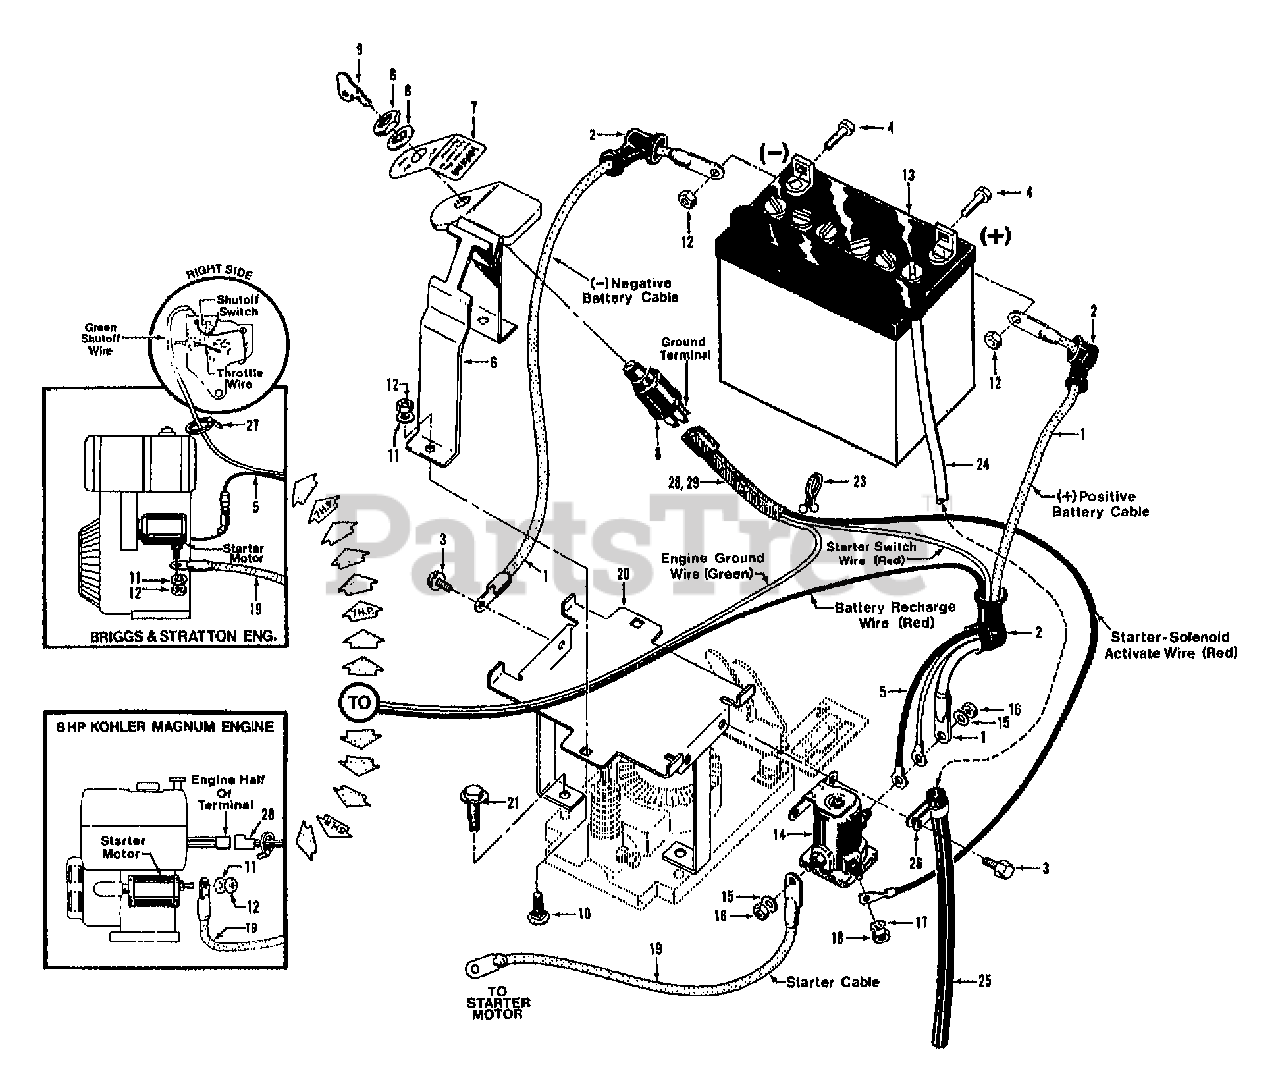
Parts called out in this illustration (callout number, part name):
1	CABLE-BATTERY 10"
2	BOOT-BATTERY CABLE
3	SCR-HWH 1/4-20 X .5 STH
4	SCR-HH 1/4-20X.625
5	WIRE-RECHARGE 5&7 BRIGGS (INCLUDES TERMINAL AND EYELET)
6	CLAMP-KEYSWITCH W/DECAL OPC
7	DECAL-KEYSWITCH
8	KEYSWITCH W/KEYS (HARDWARE NOT AVAILABLE SEPARATELY FROM GARDEN WAY)
9	KEYS(1 PAIR) FOR SWITCH
10	SCR-CARR 1/4-20X1.5
11	WASHER-LK .25 ZP
12	NUT-HEX 1/4-20 ZP
13	BATTERY-12 VOLT HORSE (COMES WITH #9009 VENT TUBE)
14	KIT-SOL W/HDW
15	WASHER-LK .312 ZP
16	NUT-HEX 5/16-24
17	WASHER-EXTERNAL TOOTH 1
18	NUT-HH M10-32X.125
19	CABLE-BATTERY 12"
20	BRKT-BATTERY OPC PNT
21	SCR-HFLK 3/8-16X1.50
23	TIE-TWIST LOCK
24	TUBE-VENT BATTERY/HSE
25	TUBING-RUBBER
26	CLAMP
27	TIE-RED
28	ASSM-HARNESS 2647/20857 (FOR BRIGGS & STRATTON ENGINE)
29	HARNESS-WIRE 3.5 (FOR KOHLER ENGINE)
